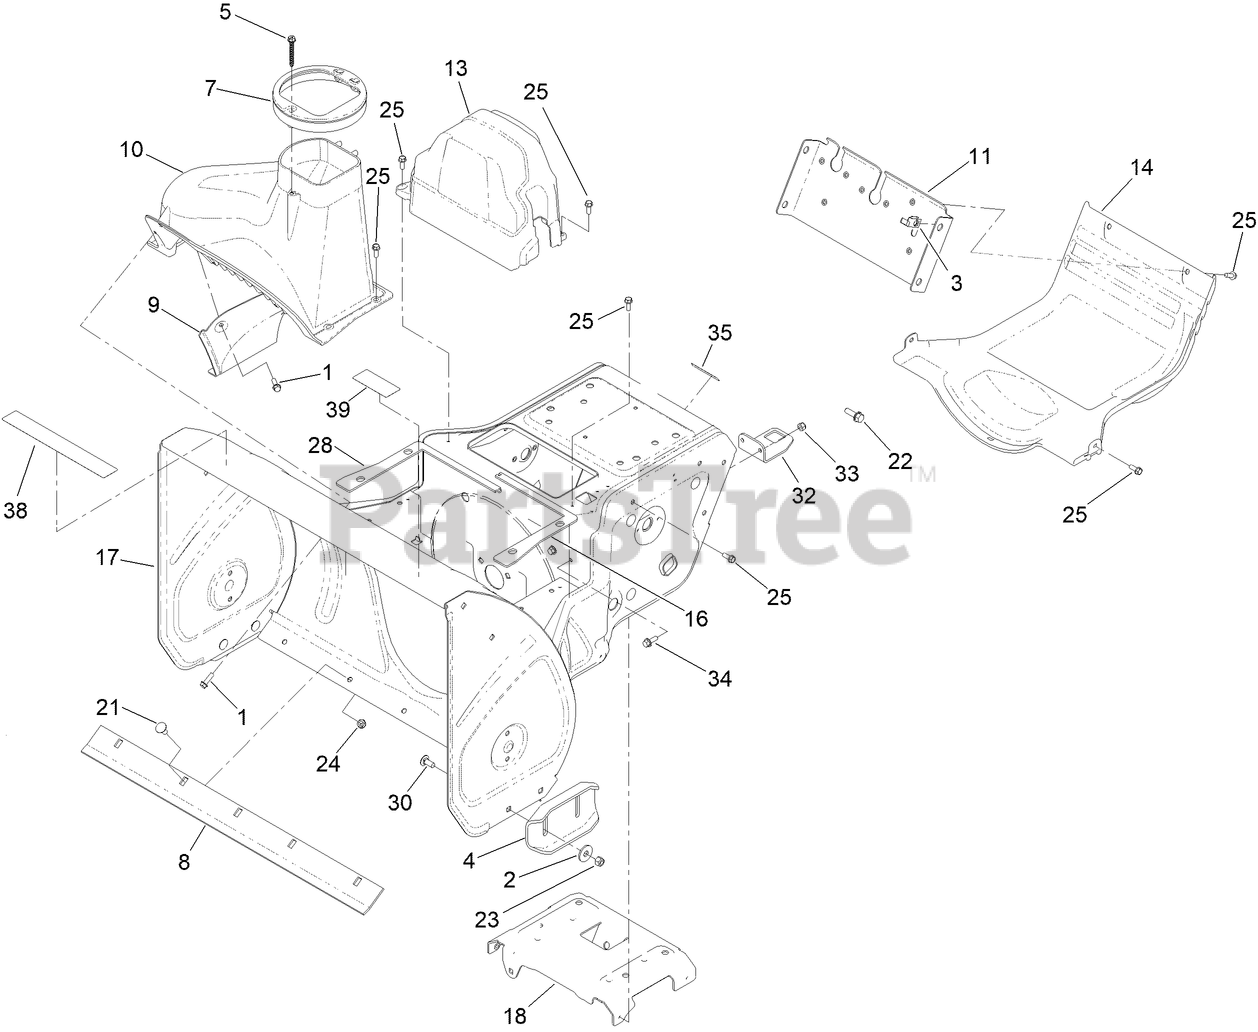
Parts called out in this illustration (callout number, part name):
1	SCREW-HWH
2	WASHER
3	NUT-U
5	SCREW-HWH, PLASTITE
7	GUIDE-CHUTE
8	SCRAPER-26 INCH
9	COVER-LINER
11	BRACE-FRAME
13	COVER-BELT
14	COVER-LOWER
16	SEAL-HOUSING, LH
17	FRAME ASM
18	BRACE-FRAME
21	SCREW-CARR
22	SCREW-HHF
23	NUT-LOCK, NI
24	NUT-LOCK, NI
25	SCREW-HWH
28	SEAL-HOUSING, RH
30	SCREW-CARR
32	BRACKET-POST, CHUTE
33	SCREW-HHF
34	NUT-HEX
35	DECAL-WARNING
38	DECAL - HARDENED GEARS
39	DECAL - COMPACT 26
